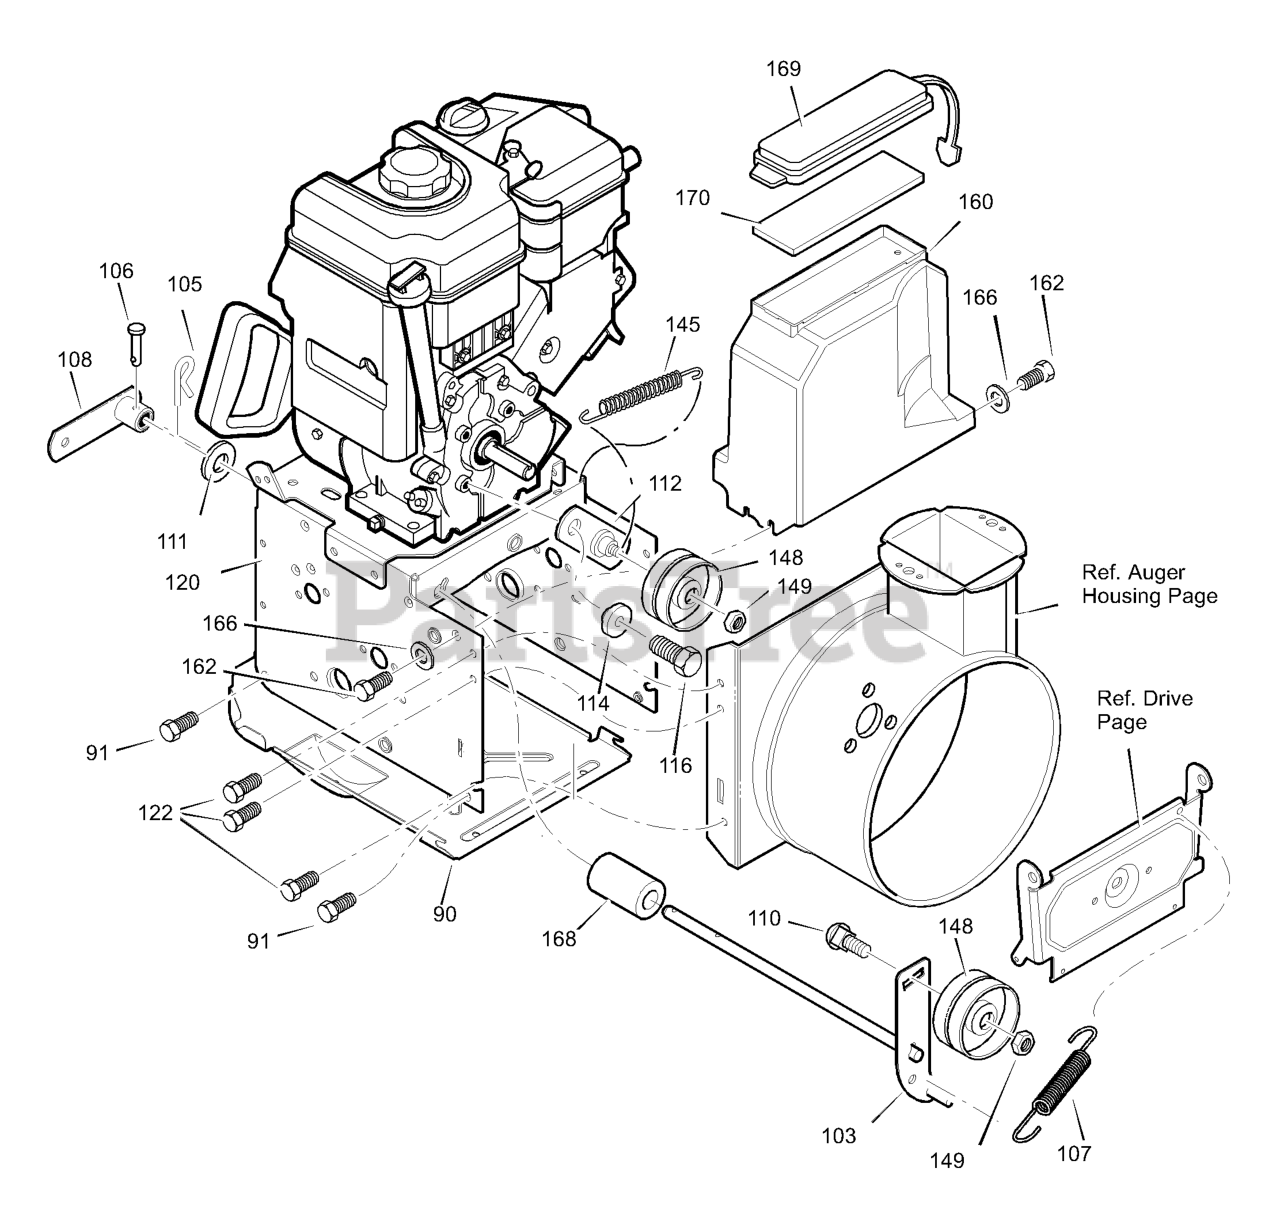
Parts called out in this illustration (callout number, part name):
90	COVER, BOTTOM
91	SCREW 1/4-20 x .63
103	IDLER ASSY, AUGER
105	PIN, HAIR
106	PIN, CLEVIS
107	SPRING, TENSION
108	ASSY., SPRING ATTACH
110	BOLT, CARR. 3/8-16 x 1.25
111	WASHER, FLAT
112	BRACKET ASSY, IDLER
114	BUSHING, IDLER BRACKET
116	SCREW, 5/16-24 x 0.75
118	WASHER, SPLIT
122	SCREW, TAP 5/16-18 x .50
145	SPRING, IDLER TRACTION DRIVE
148	PULLEY, IDLER
149	NUT, JAM 3/8-16
160	COVER, BELT
162	SCREW, TAP
166	WASHER, FLAT
168	SPACER, AUGER BRACKET
169	LID, TOOL BOX
170	PAD, FOAM
